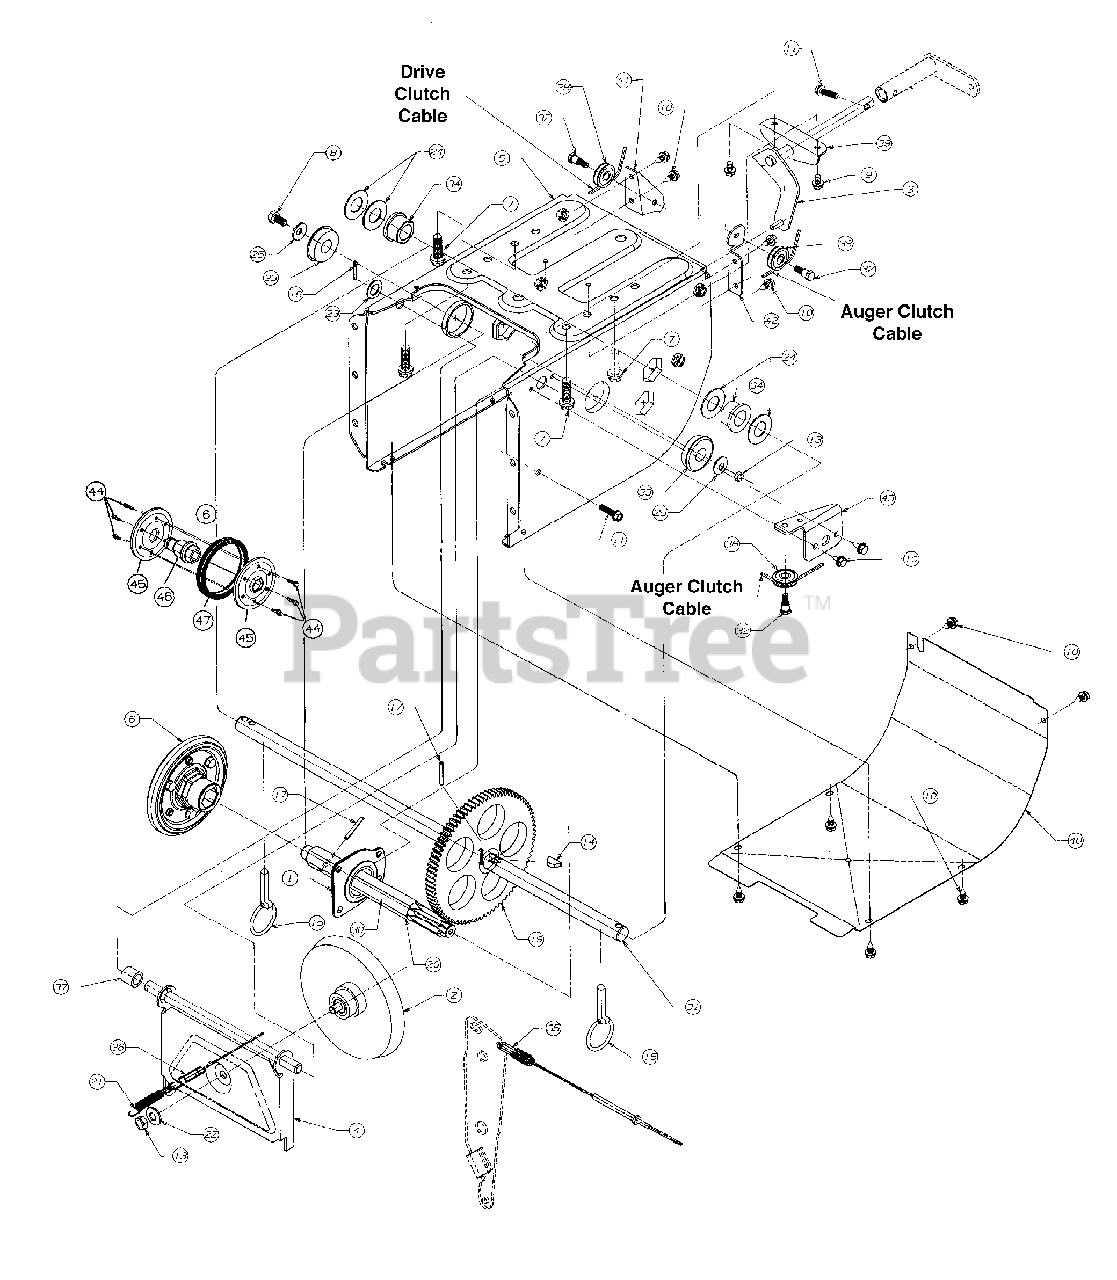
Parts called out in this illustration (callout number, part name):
1	Bearing Ass'y.
2	Ass'y., Friction Wheel Disc
3	Rod Shift, Wheel Drive
7	Hex Self - Tap Screw
9	Scr., Hex Wash. Hd.,TT-1/4-20 x .5"
10	Hex Self - Tap Scr.
11	Screw, Hex
13	Nut, Hex
15	Pin, Klick
16	Pin, Cotter
17	Pin, Roll Guide
20	Shaft, Hex Scr.1/4-20 x .5" Lg.
21	Extension Spring
22	Washer, Bell
23	Flat Washer
24	Washer, Flat
25	Washer, Bell
30	Lubricant
31	Axle Used with 13" Wheels
31	Axle Used with 16" Wheels
32	Screw, Shoulder
33	Bearing, Ball
34	Flange Bearing
35	Cable, Auger
36	Cable, Clutch
37	Spacer
38	Roller, Cable
45	Friction Plate
46	Friction Wheel Hub
47	Friction Wheel Rubber
